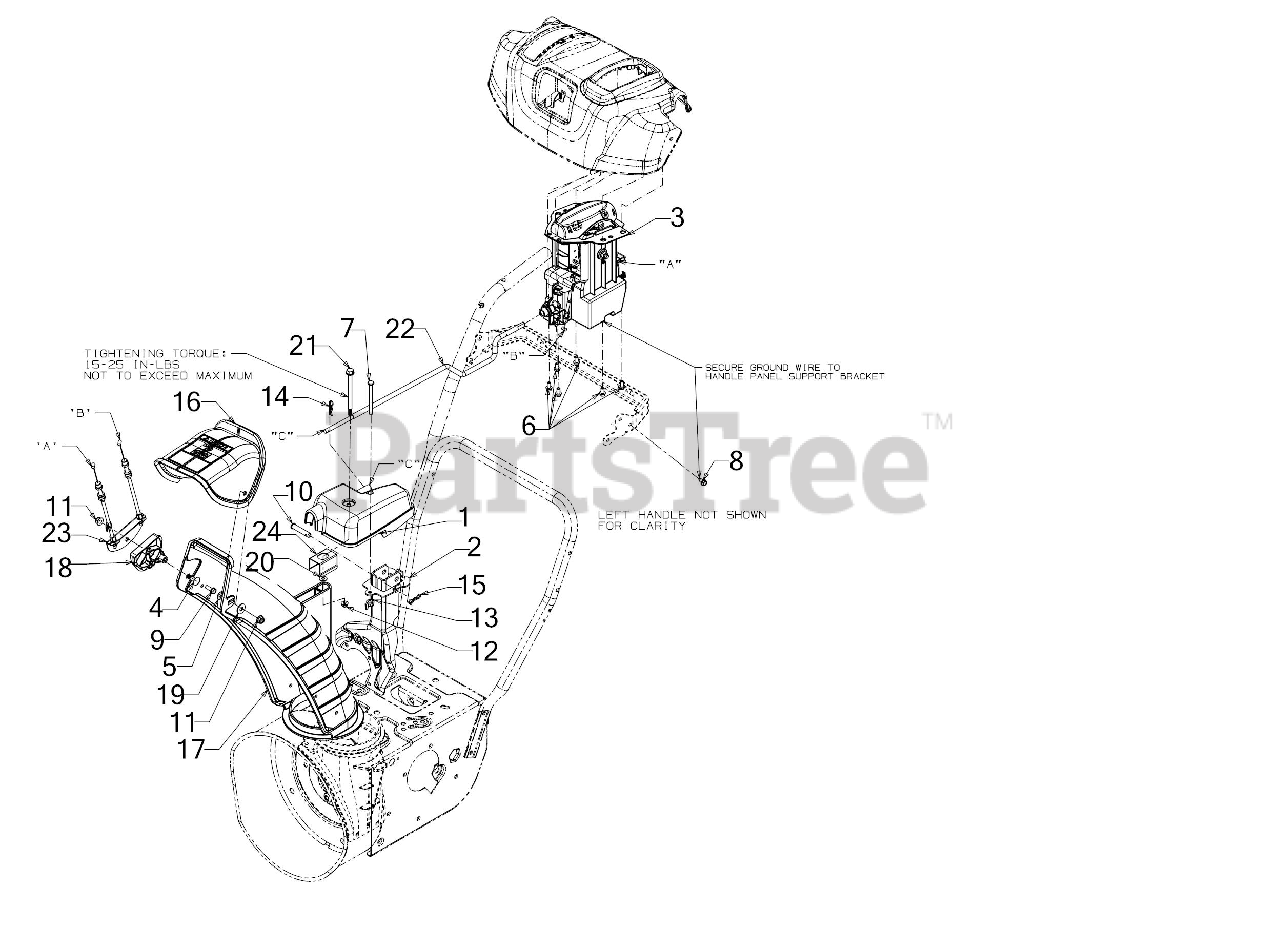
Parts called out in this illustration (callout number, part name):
1	WORM GEARBOX ASSEMBLY
2	CHUTE SUPPORT BRACKET ASSEMBLY
3	4-WAY CHUTE CONTROL ASSEMBLY
4	CARRIAGE BOLT 5/16-18 x 1.50
5	CARRIAGE BOLT 5/16-18 x 1
6	HEX SCREW 1/4-15 x .50
7	SCREW 1/4-20 x 3.0 GR5
8	SCREW 1/4-20 X.500
9	SCREW 1/4-15 x .750
10	CLEVIS PIN 3/8 x 1.87
11	FLANGE LOCK NUT 5/16-18
12	FLANGE LOCK NUT
13	WING NUT 1/4-20
14	INTERNAL COTTER PIN
15	BOW TIE COTTER PIN 1/4-5/16
16	UPPER REMOTE CHUTE WITH LABEL
17	LOWER CHUTE 5" DIA
18	CABLE CHUTE GUIDE
19	FLAT WASHER
20	FLAT WASHER
21	SHOULDER SCREW
22	ELECTRIC CHUTE CRANK ROD
23	CABLE BRACKET
24	CHUTE BRACKET
